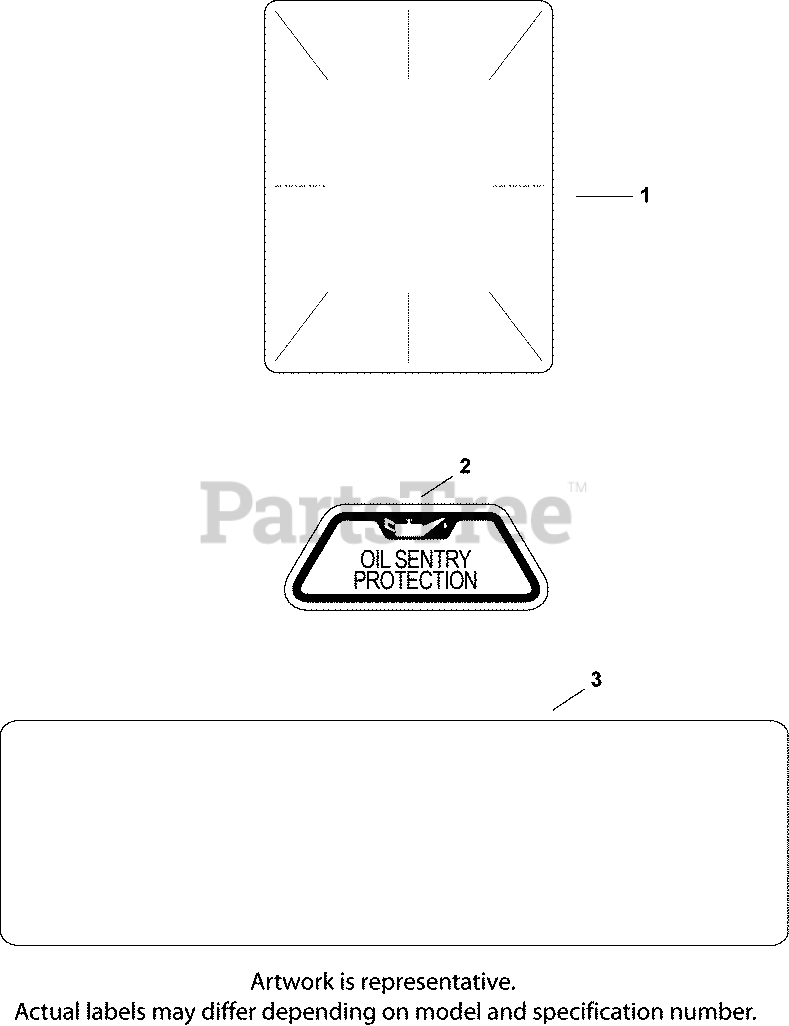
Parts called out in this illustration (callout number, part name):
1	DECAL, CLEAR LAMINATE USE 25 113 70-S
2	DECAL, OIL SENTRY - (#DSC)
3	DECAL, 20 HP - DISCONTINUED
